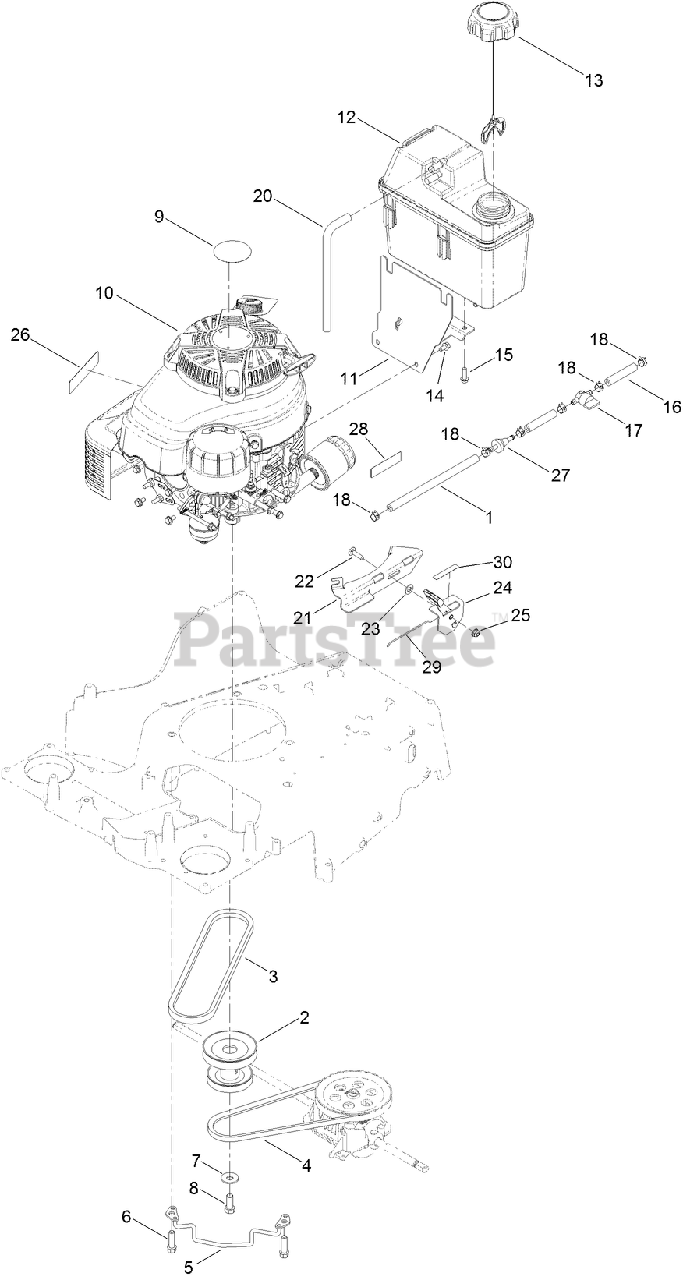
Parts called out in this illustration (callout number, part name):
1	HOSE-FUEL
2	PULLEY-ENGINE
3	V-BELT
5	GUIDE-BELT
6	SCREW-TAPTITE
7	WASHER-BELLEVILLE
8	SCREW-HH
9	Decal-Recoil
11	MOUNT-TANK
12	TANK-FUEL
13	CAP-RATCHET, TETHERED
14	SCREW-HWH
15	SCREW-HWH
16	HOSE-FUEL
17	VALVE-FUEL
18	CLAMP-HOSE
20	HOSE-VENT, CANISTER
21	BRACKET-MOUNT, THROTTLE
22	SCREW-CARR
23	WASHER-PLAIN
24	CONTROL-THROTTLE
25	NUT-HF
26	DECAL-ARRESTER, SPARK
27	FILTER-FUEL
28	DECAL-WARNING, ENGINE
29	WIRE-CONTROL
30	DECAL-THROTTLE, CHOKE
